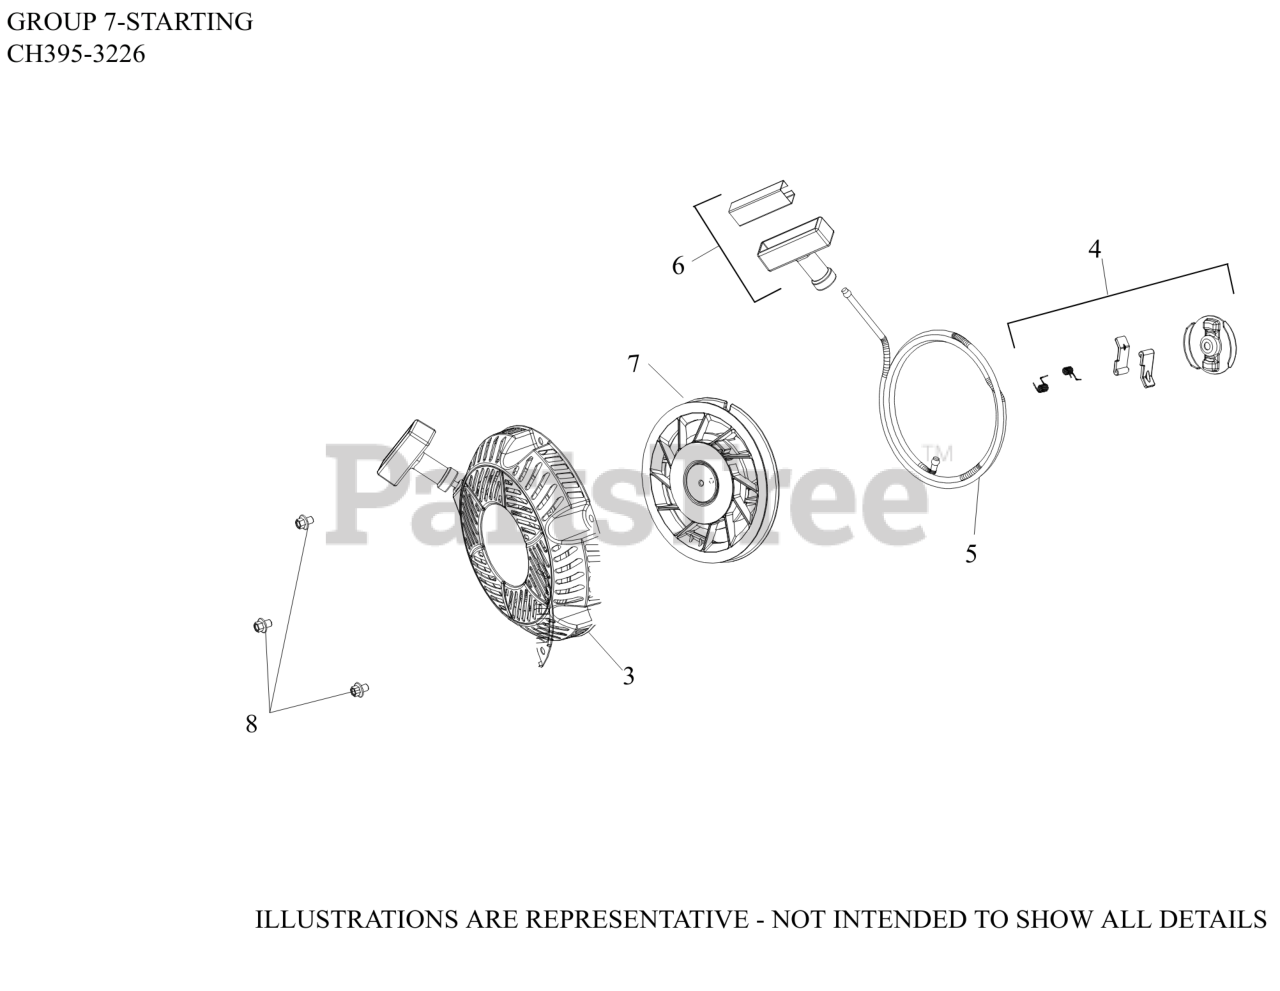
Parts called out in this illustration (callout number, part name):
3	RETRACTABLE STARTER ASSEMBLY
4	KIT, PAWL REPAIR
5	KIT, ROPE
6	KIT, HANDLE
7	PULLEY, RECOIL
8	SCREW, M6 X 8 HEX FLANGE HEAD
